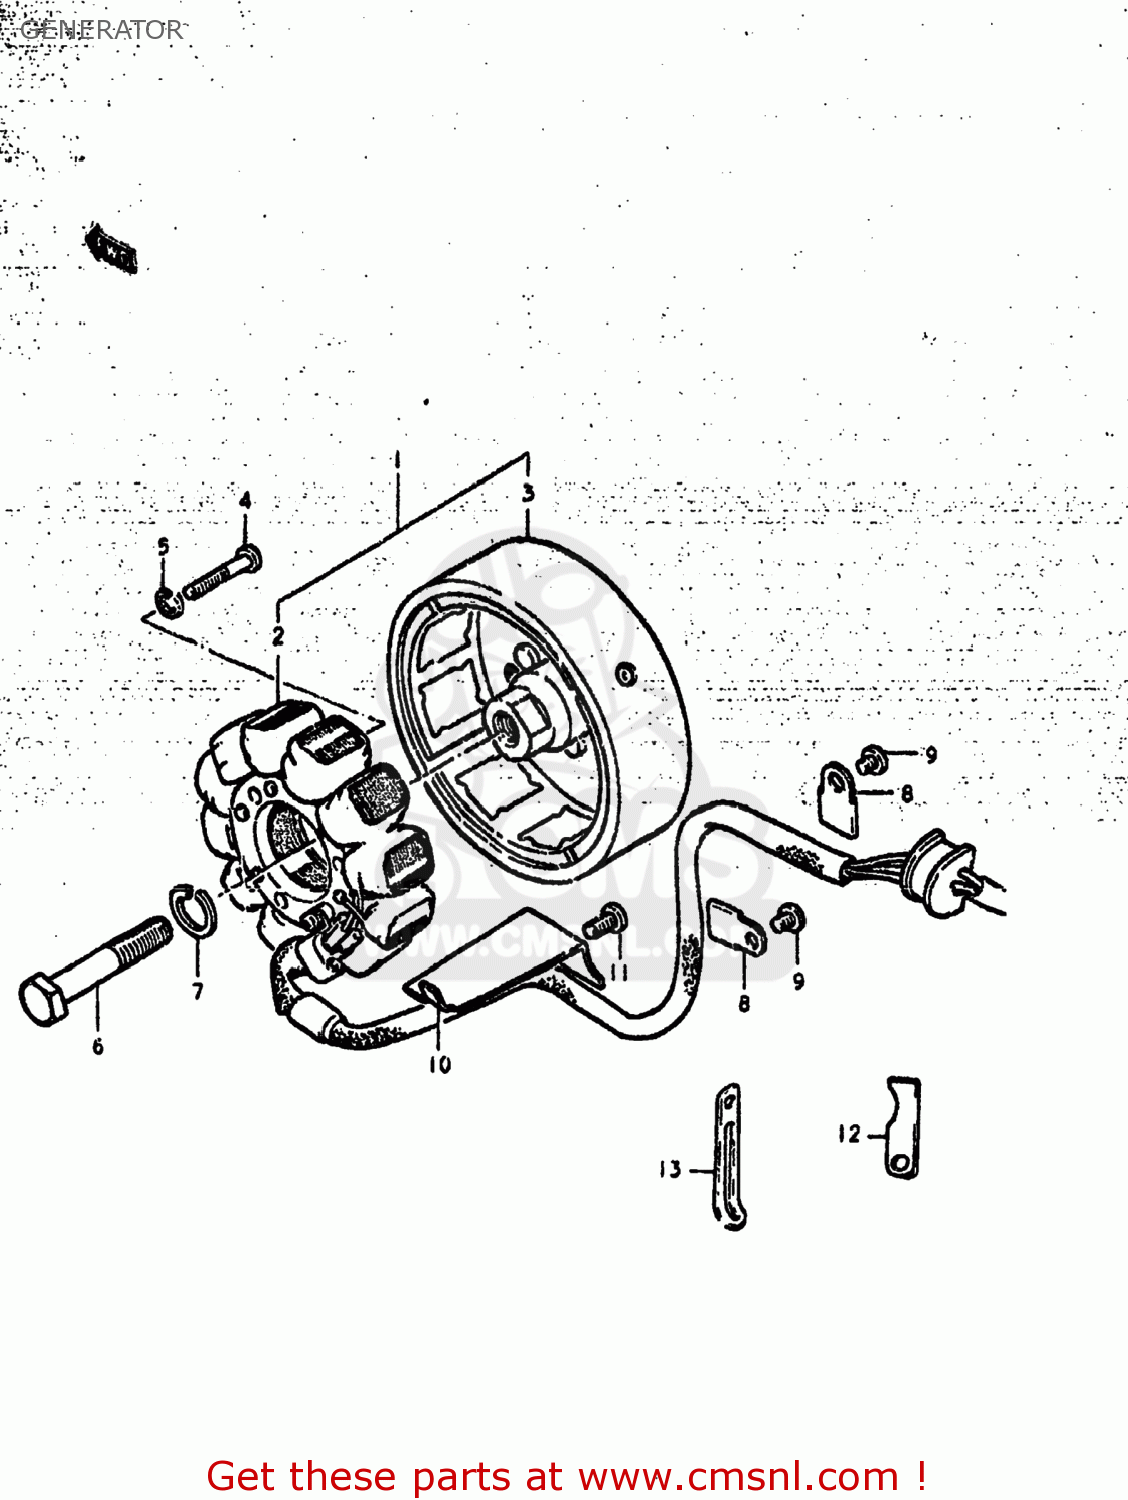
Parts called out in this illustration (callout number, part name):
1	GENERATOR ASSEMBLY
2	STATOR ASSEMBLY
3	ROTOR ASSEMBLY
4	SCREW
5	LOCK WASHER
6	BOLT 12X45
7	WASHER,LOCK 12
8	CLAMP,GENERATOR LEAD WIRE
9	SCREW
10	CLAMP,GENERATOR LEAD WIRE
11	SCREW
12	CLAMP,GENERATOR LEAD WIRE
13	CLAMP L:35
